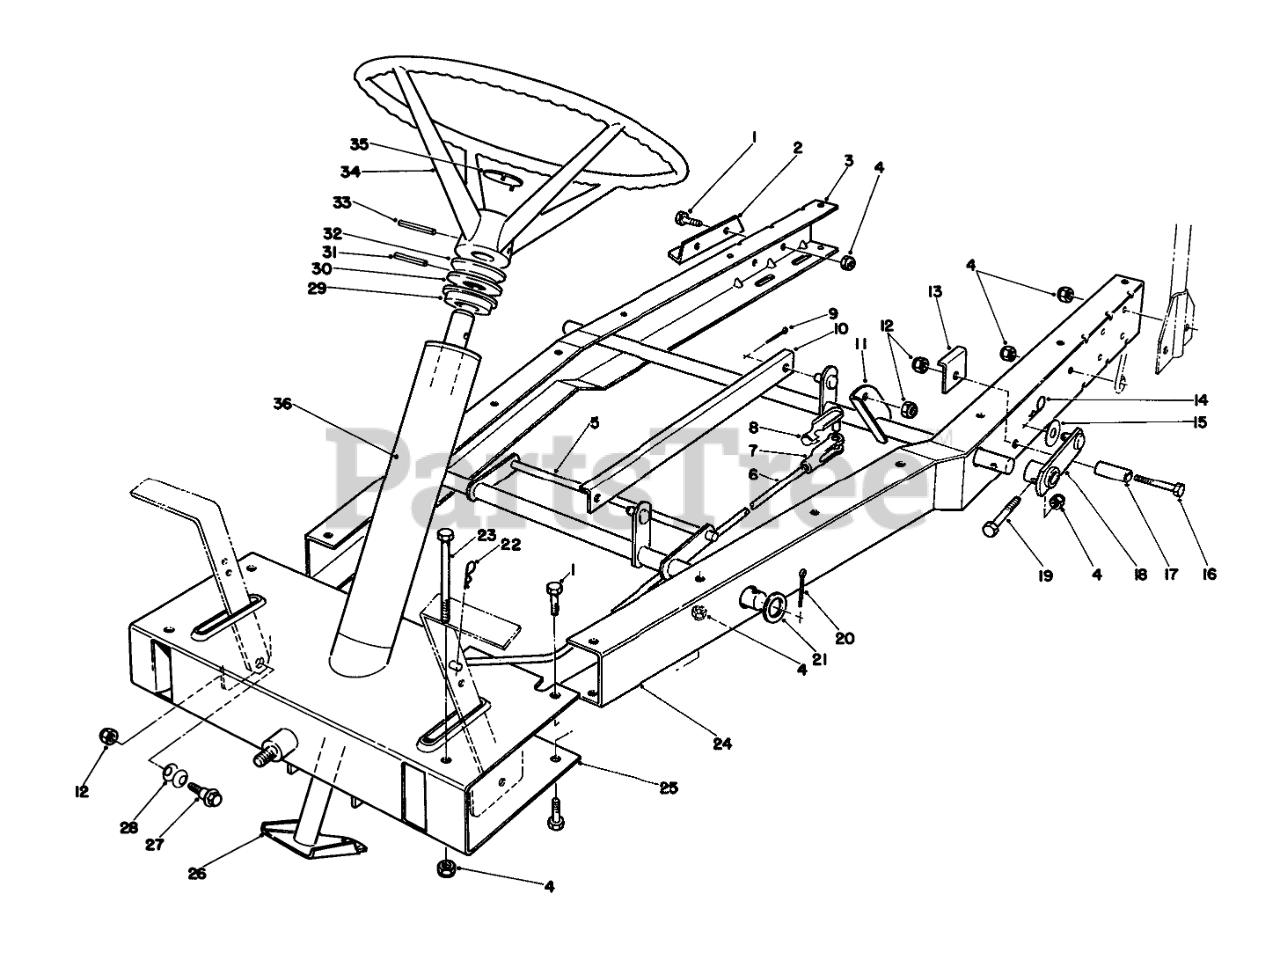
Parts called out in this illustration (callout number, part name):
1	SCREW-HH
2	Mount-Axle Brg.
3	Channel-R.H.
4	NUT-LOCK, NI
5	Deck Lift W.A.-Front
6	ROD-CLUTCH
7	CLEVIS-ADJ
8	CLEVIS PIN ASM
9	PIN-COTTER
10	Bracket-Hoc Link
11	Tube W.A.-Rear Support
12	NUT-LOCK, NI
13	Brace-Deck Stop
14	PIN-HAIR
15	WASHER
16	SCREW-HH
17	SPACER-STOP,DECK
18	Lever W.A.-Hoc
19	AXLE MTG BOLT
20	PIN-COTTER
21	WASHER-FLAT
22	PIN-COTTER
23	SCREW-HH
24	Channel-L.H.
25	Frame W.A.-Front
26	Shaft W.A.-Steering
27	BOLT-SHOULDER
28	WASHER-BELLEVILLE
29	BUSHING-STEERING
30	WASHER-STEERING
31	PIN-ROLL
32	SPACER-STEERING
33	PIN-ROLL
34	STEERING WHEEL ASM
35	STEERING WHEEL INSERT
36	DECAL - STEERING COLUMN
